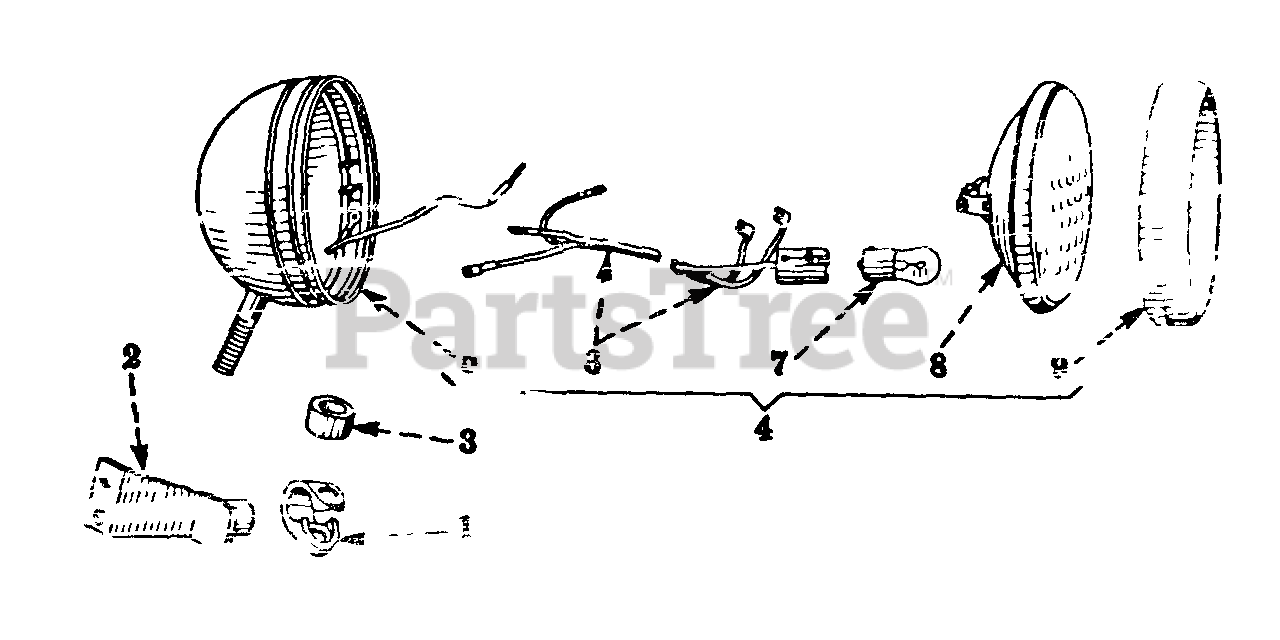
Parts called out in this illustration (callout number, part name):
1	CLAMP, REAR LIGHT
2	BRACKET ASSY, REAR LIGHT
3	LIGHT ASSY, COMBINATION REAR AND TAIL - SEALED BEAM
4	BODY, REAR LIGHT
7	MOULDING, REAR LIGHT
